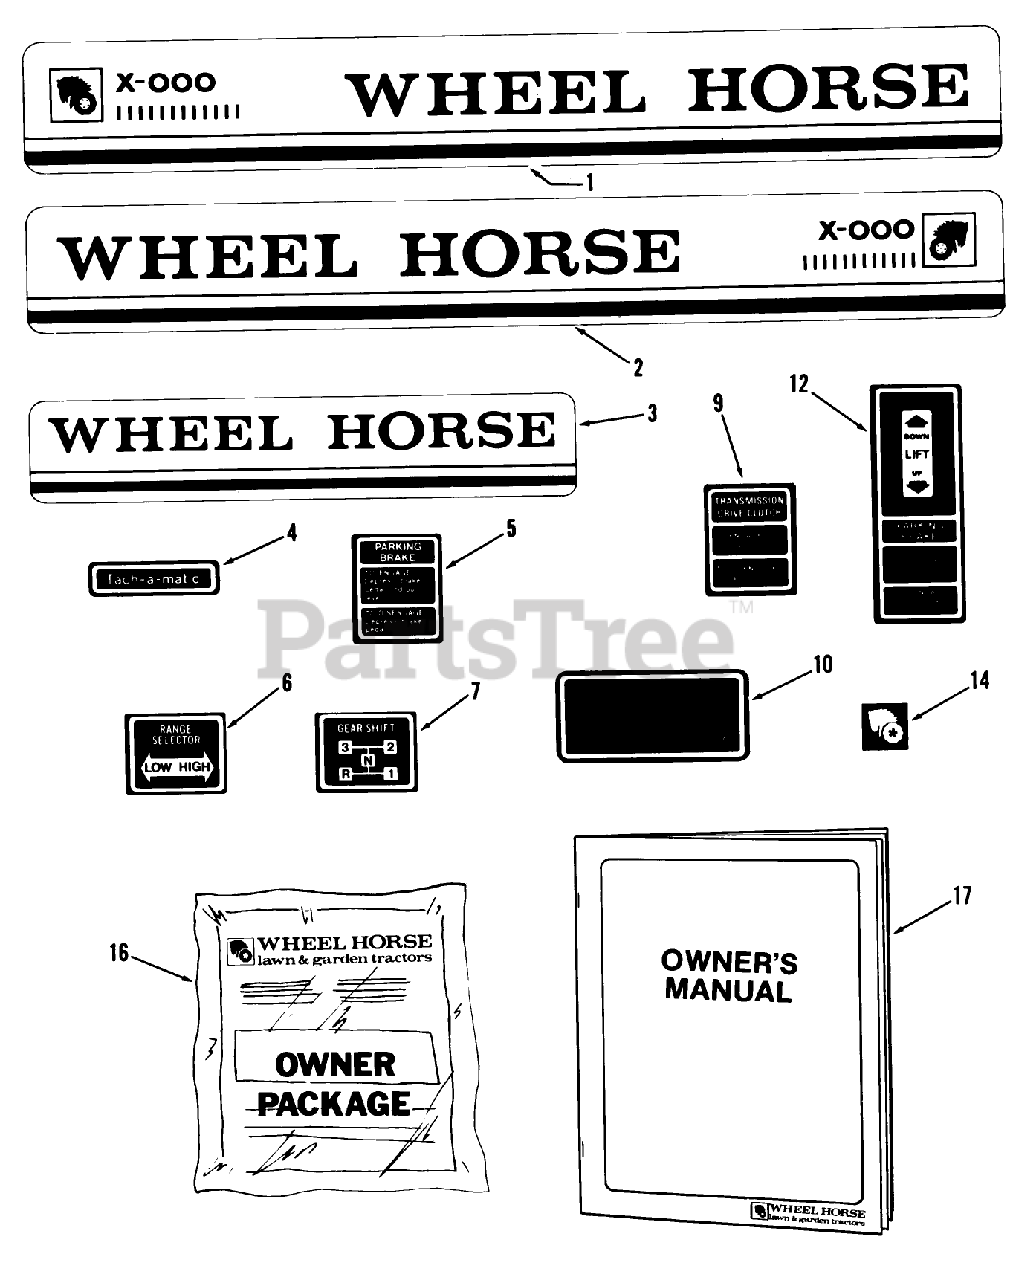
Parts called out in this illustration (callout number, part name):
2	Decal RH C-175 Twin Automatic
3	DECAL-REAR
5	DECAL-PARKING BRAKE
6	DECAL, RANGE SELECTOR
12	Decal-Parking Brake Lift
14	DECAL-LOGO
16	Loose Parts Package C-165 Only
17	Owner-s Manual-Tractor
